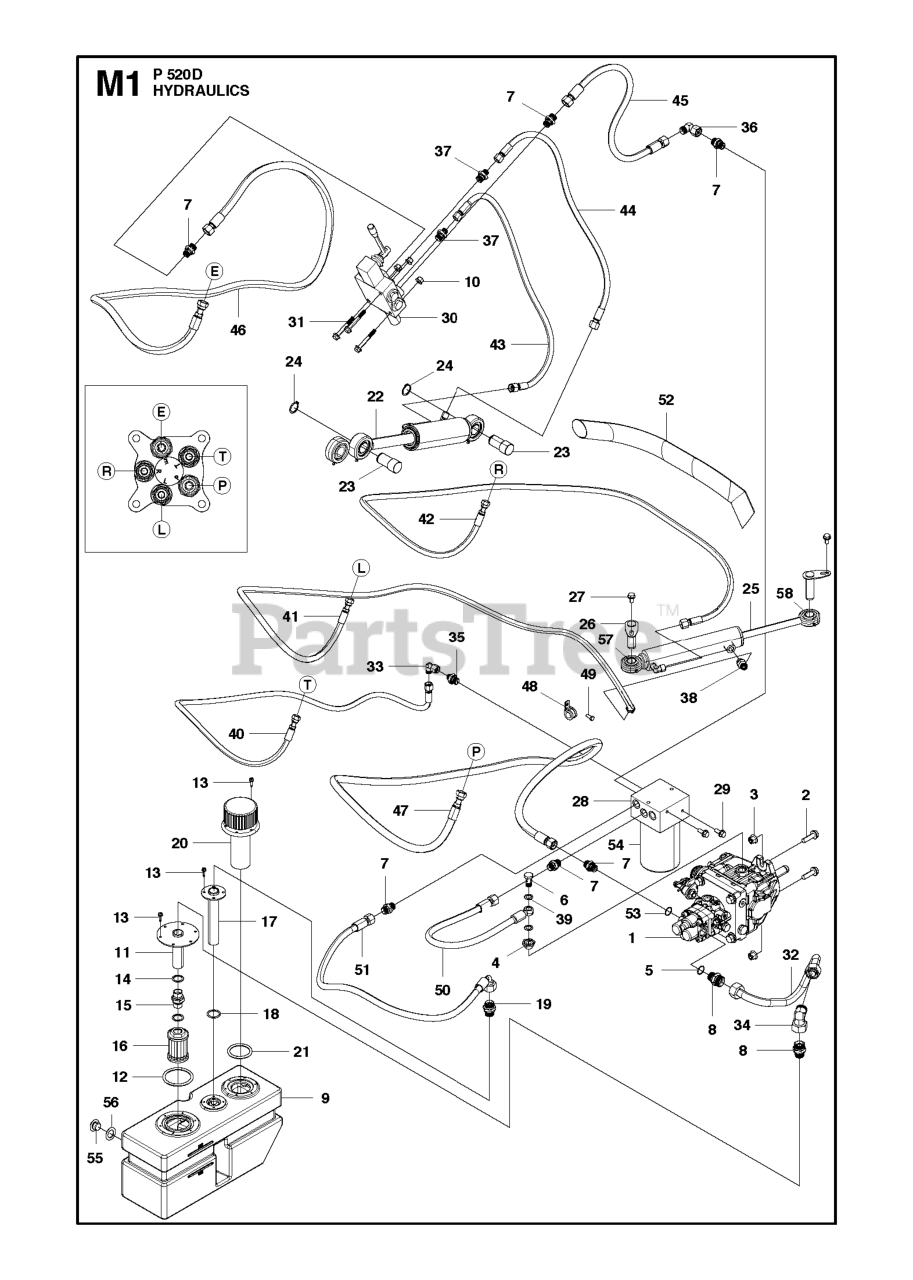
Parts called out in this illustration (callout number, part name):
10	NUT FLANGE
12	O-RING 61.2X5.7 NITRIL
15	PIPE FITTING G STRAIGHT 1/2-1/
16	FILTER PUMP SUCTION, AWD
18	O-RING 26.2X3.0 NITRILE
21	O-RING 47.2X5.7 NITRIL
24	RETAINING RING SGA 25
39	GASKET 20X14X1.5 COPPER
48	HOSE CLAMP
53	REPL BY 740 48 14-02
